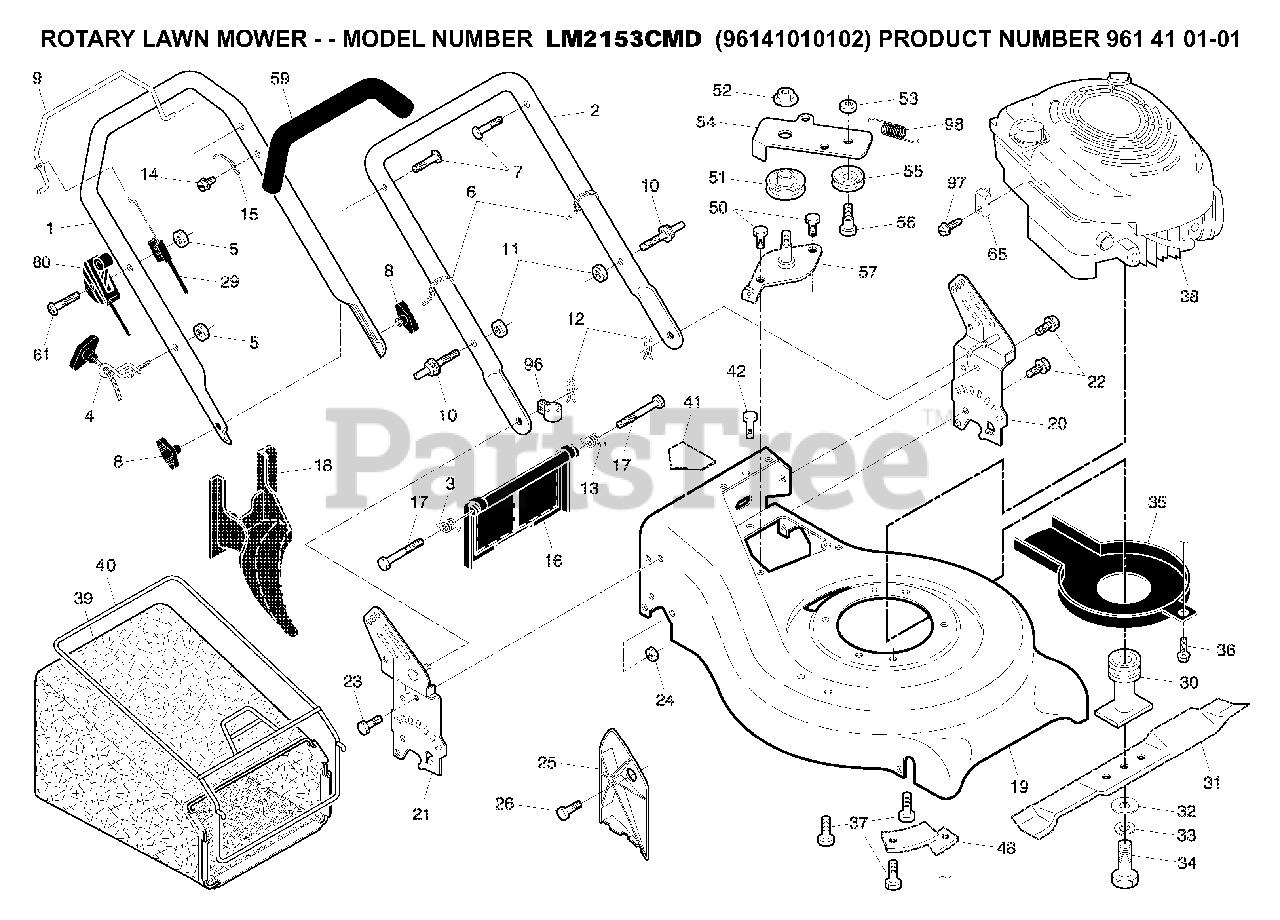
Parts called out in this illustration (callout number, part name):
2	HANDLE LOWER
3	SPRING.RH.REAR.DOOR.21.RWGD
4	GUIDE.ROPE.STD.BLK.ZIN
5	NUT
6	TIE GUIDE
7	BOLT, HANDLE 5/16-18X1.75
8	KNOB, DEFLECTOR
11	NUT, LOCK 5/16-18
12	HAIRPIN COTTER
13	SPRING.LH.REAR.DOOR.21.RWGD
15	BRACKET UPSTOP
16	REAR DOOR ASSEMBLY
18	PLUG.MULCHER.RGD.21.
20	BRKT.ASM HNDL
21	BRKT.ASM.HNDL
22	SELF-TAPPING SCREW 5/16-18X3/4
23	BOLT, HEX HEAD 5/16-18
24	NUT.71038.31-18.HEX.NYLOCK
25	CLIPPING DEFLECTOR
29	ENGINE ZONE CONTROL
30	BLADE ADAPTOR / PULLEY
31	BLADE.21.PUSH
32	WASHER,HARDEN
33	LOCKWASHER
34	SCREW, HEX HD 3/8-24 X 1-3/8
35	DEBRIS SHEILD
36	SCREW.HEX.WSH
37	BOLT 3/8-16X1-1/8
40	FRAME, GRASSBAG
41	DECAL.INTERNATIONL.CUTFINGER
48	BRACKET
51	PULLEY.IDLER
52	NUT.HEX.FLANGE.3/8-16.LOCKNUT
54	ARM.IDLER
55	IDLER PULLEY
57	BRACKET.IDLER.ASM.EZ
59	GRIP.HANDLE.FOAM
60	CONTRL.THROTTLE.
65	CABLE CLAMP(ENGINE)
96	CLIP.CABLE.BLK
97	SCREW.HEX.HEAD.WASHER.10-16
